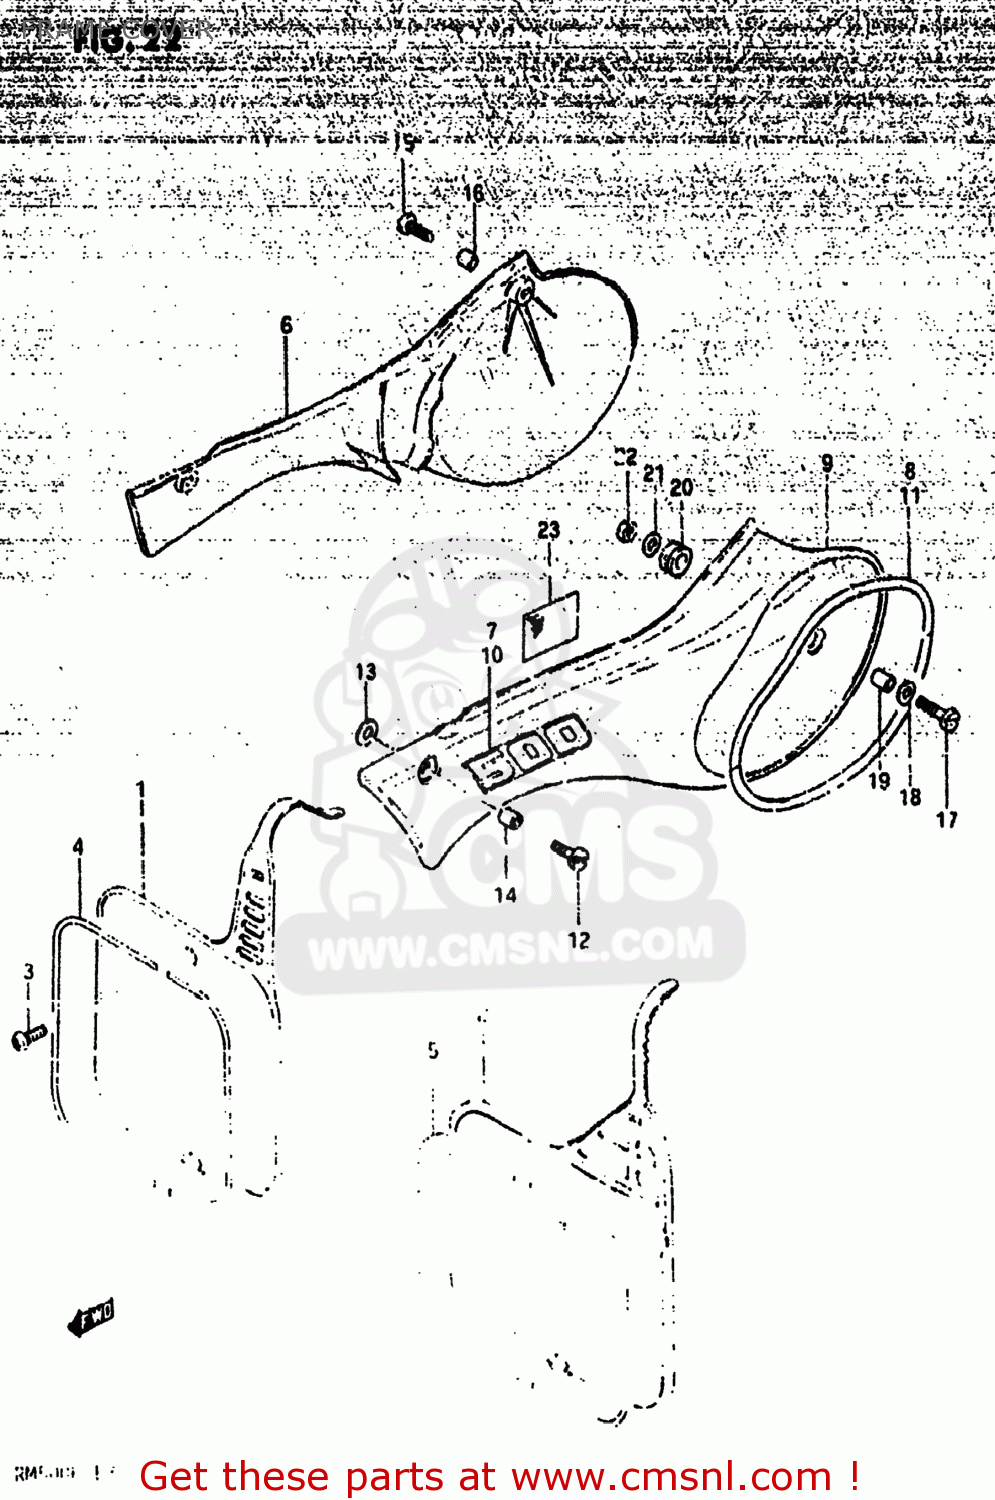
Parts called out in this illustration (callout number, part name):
1	PLATE,NUMBER,FRONT
2	PLATE,NUMBER,FRONT
3	SCREW
4	TAPE,SET
5	TAPE,SET
6	COVER,FRAME,R(YELLOW)
7	EMBLEM
8	TAPE SET,FRAME COVER
9	COVER,FRAME,L(YELLOW)
10	EMBLEM,FRAME COVER
11	TAPE SET,FRAME COVER,RIGHT
12	SCREW(6X14)
13	WASHER, REAR
14	SPACER (6.1X8X3.5)
15	SCREW(6X14)
16	SPACER (6.1X8X3.5)
17	SCREW(6X20)
18	WASHER (6.5X24X1.6)
19	SPACER (6.1X9X9)
20	CUSHION
21	WASHER, REAR
22	NUT 6MM
23	HEAT SHIELD,FRAME COVER
